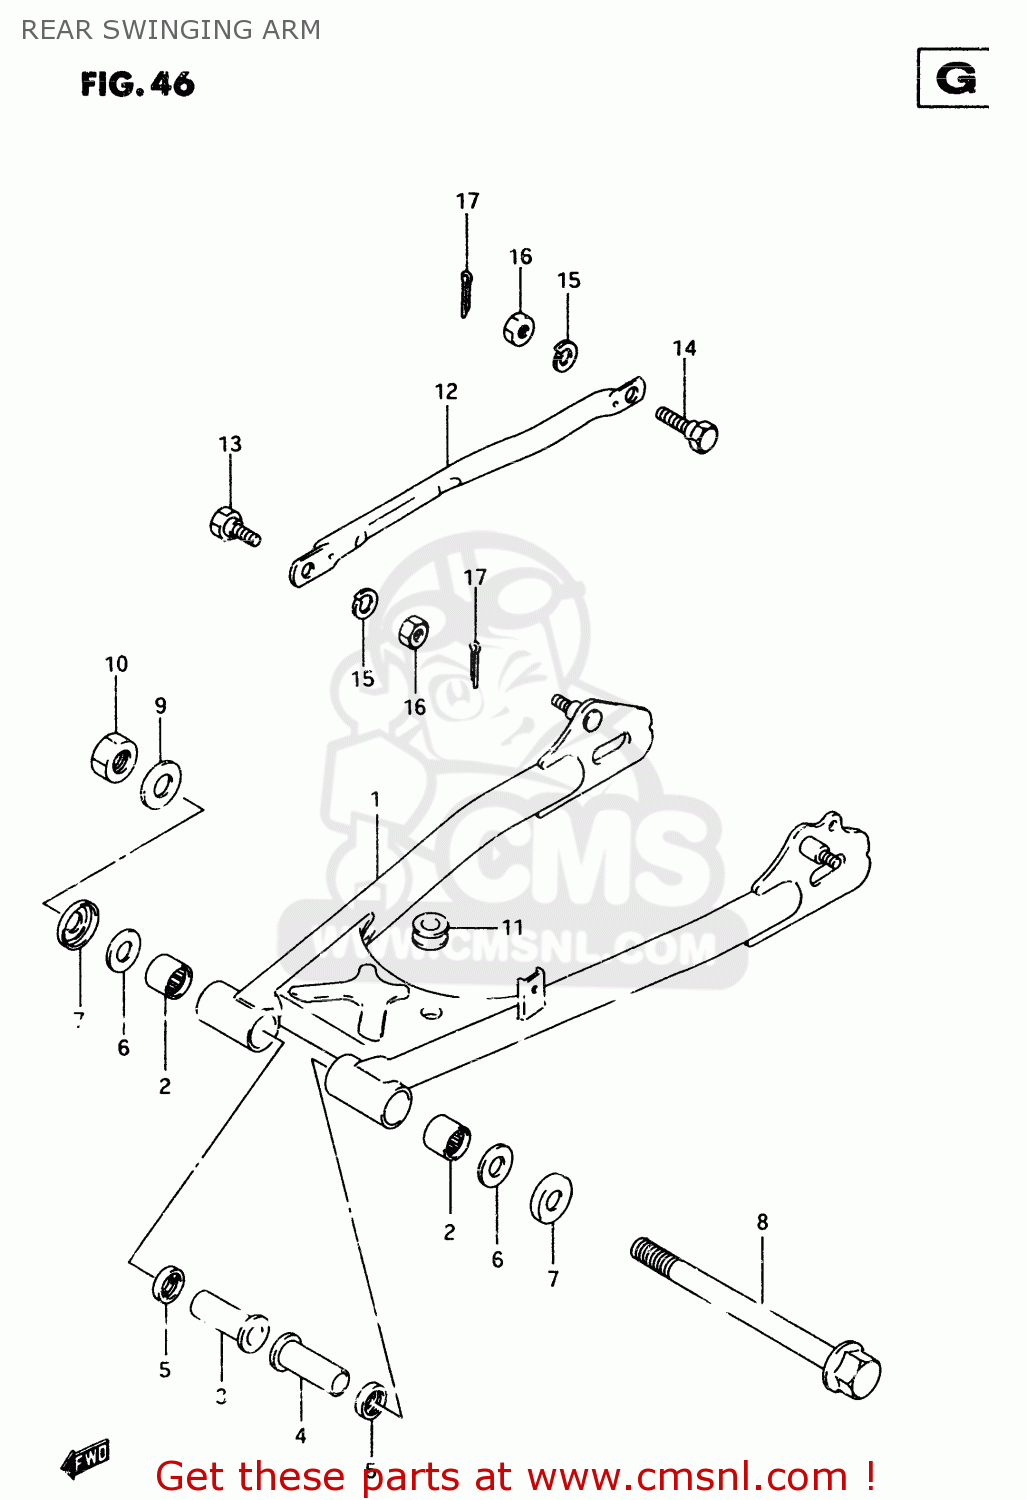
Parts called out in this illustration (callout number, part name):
1	SWINGINGARM ASSY,RR
2	BEARING(20X27X20)
3	SPACER,RR SWGARM PIVOT,R
4	SPACER,RR SWGARM PIVOT,L
5	SEAL,OIL(20X27X5)
6	WASHER
7	COVER,RR SWINGINGARM PIVOT
8	SHAFT,RR SWINGINGARM PIVOT
9	WASHER
10	NUT 14MM
11	CUSHION
12	TORQUE LINK,REAR BRAKE (
13	BOLT(8X22.5)
14	BOLT(8X26.5)
15	WASHER,LOCK
16	NUT
17	PIN 20X20
